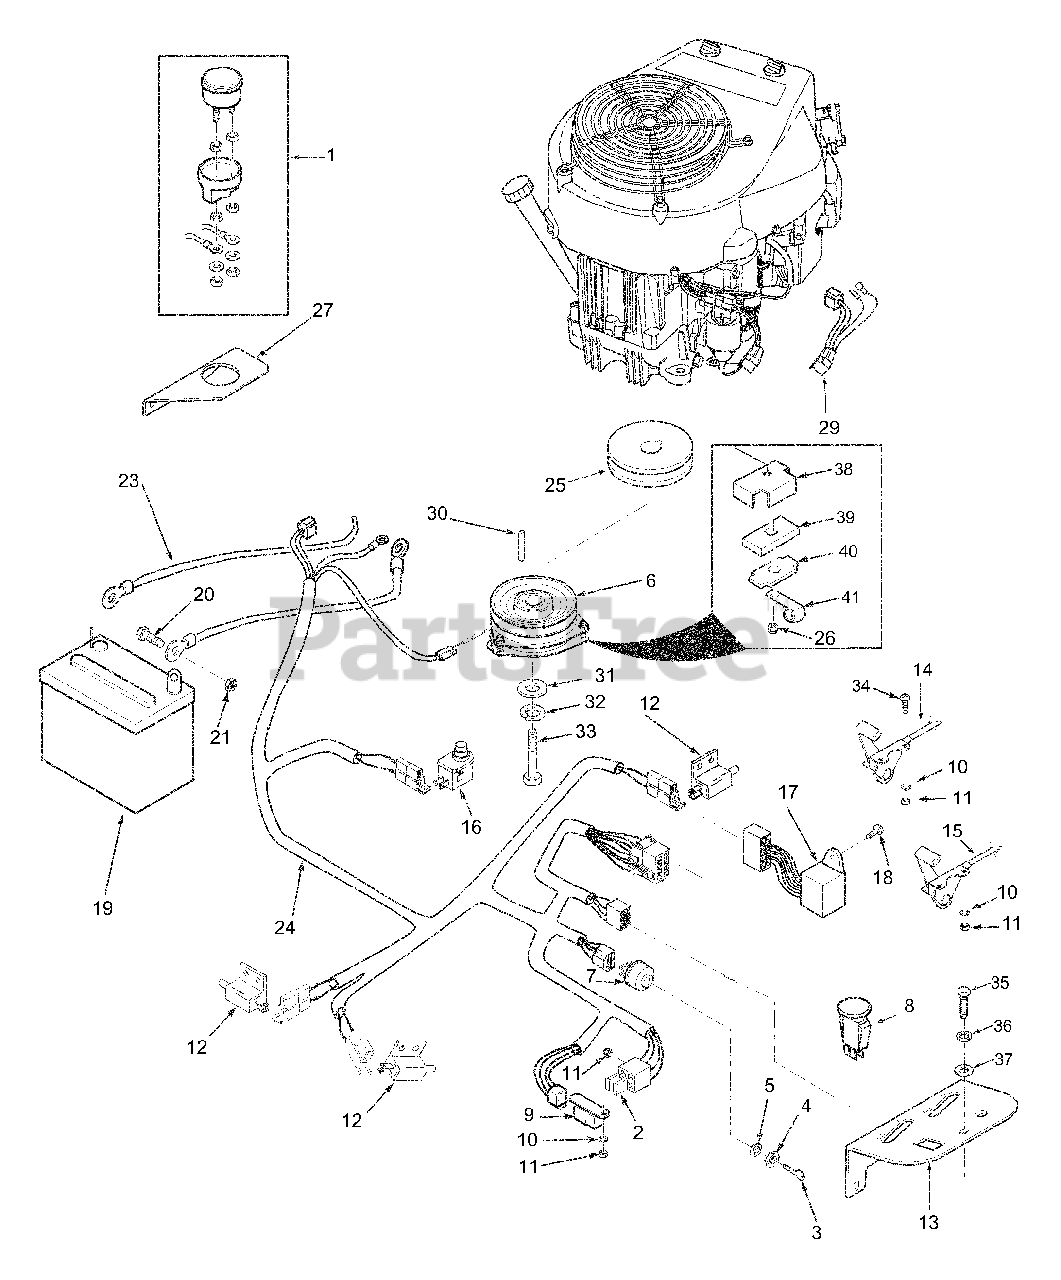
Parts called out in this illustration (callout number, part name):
1	Hourmeter
2	Fuse, 20 amp
3	Key, Ignition
4	Nut, Hex 5/8-32
5	Lockwasher, 5/8" Internal
6	Electric PTO Clutch (48A & 52A)
7	Switch, Ignition
8	Switch, PTO
9	Relay
10	Lock Washer, #10 External Tooth
11	Nut, Hex #10-32
12	Switch, N/O
13	Panel, Instrument
14	Choke & Throttle Control - Kawasaki (Qty 2)
15	Throttle Control - Kohler ( Qty 1)
16	Switch, Seat
17	Module, Interlock
18	Screw, #10-32 x .5" Phillips Head
19	Battery
20	Bolt, Hex Head 1/4-20 x .5"
21	Nut, Hex 1/4-20
23	Cable, Battery Red (positive)
24	Wiring Harness, Main
25	Pulley, 5.45 OD x 1.125 Bore
26	Nut, Elastic Stop 5/16-18 Key
27	Mounting Bracket, Hour Meter
29	Adaptor, Wiring Harness (Kawasaki only)
30	Key, 1/4 x 1/4 x 3-1/4"
31	Flatwasher, 7/16-.469 x 1-3/4" x 1/4"
32	Lockwasher, 7/16"
33	Bolt, Hex Head 7/16-20 x 2-1/2" UNF
34	Screw, #10-32 x 3/4"
35	Bolt, Hex Head 5/16-18 x 3/4"
36	Lockwasher, 5/16
37	Flatwasher, 5/16-.375 x .875 x .083
38	Backing Plate
39	Rubber Pad, Clutch Stop
40	Plate, Backing
